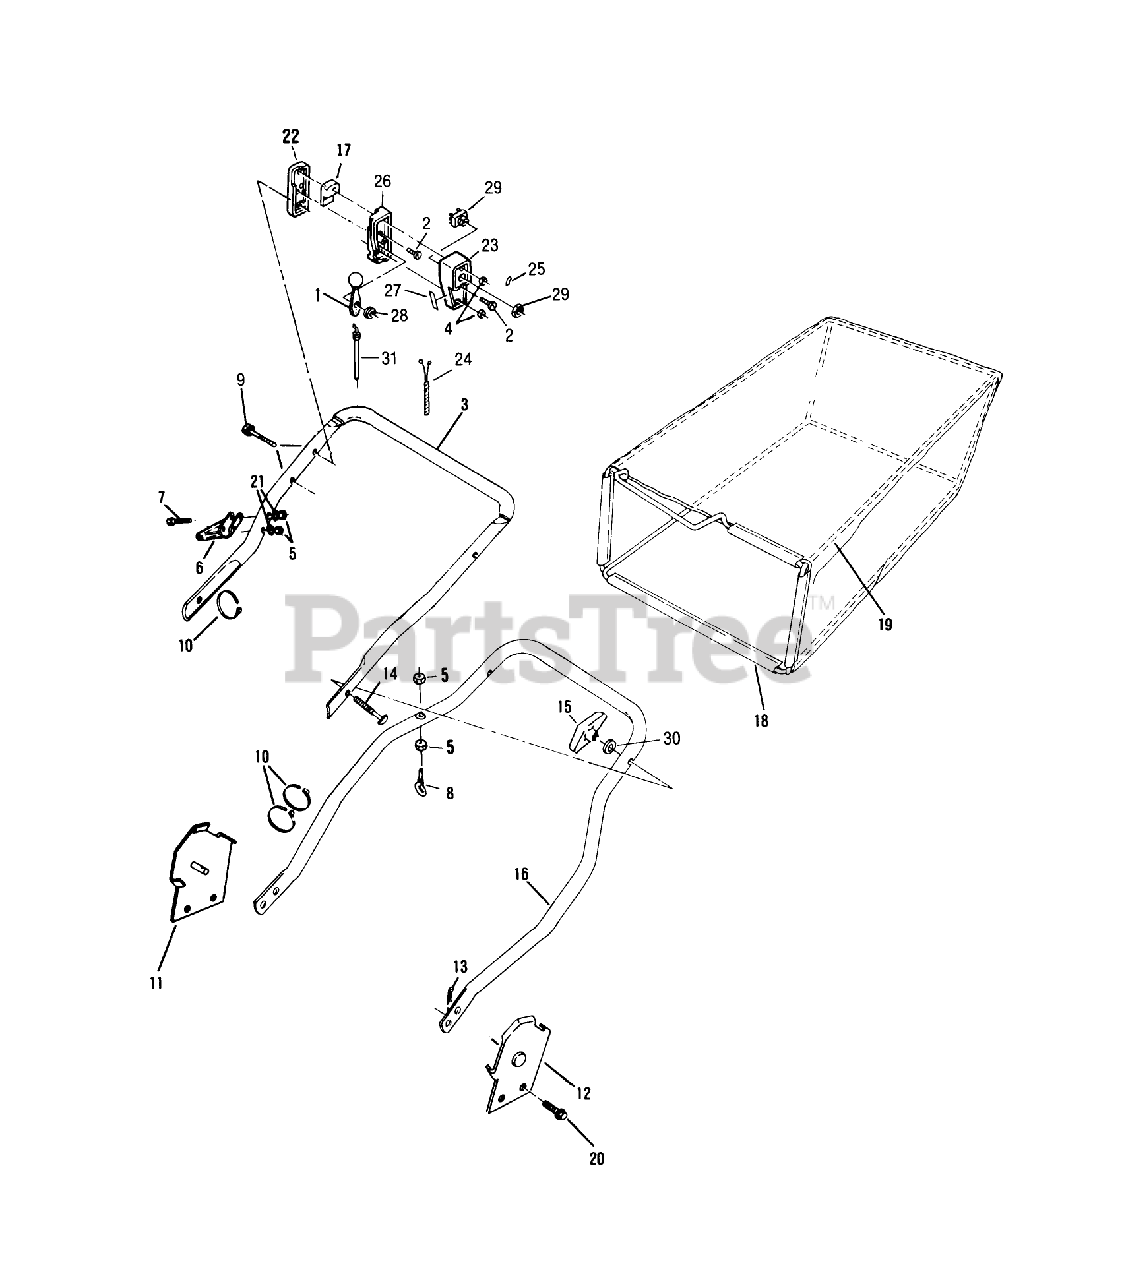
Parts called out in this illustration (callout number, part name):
1	LEVER&KNOB AY WES
2	SCREW
4	NUT C/LOCK E
5	LOCKNUT E
8	EYE BOLT WAS MFG
9	SCREW
13	HAIR PIN
14	BOLT QUALITY
15	NUT-WING
21	WASHER
28	WASHER-SPRING
30	WASHER-CURVED
31	CABLE THROT WES
